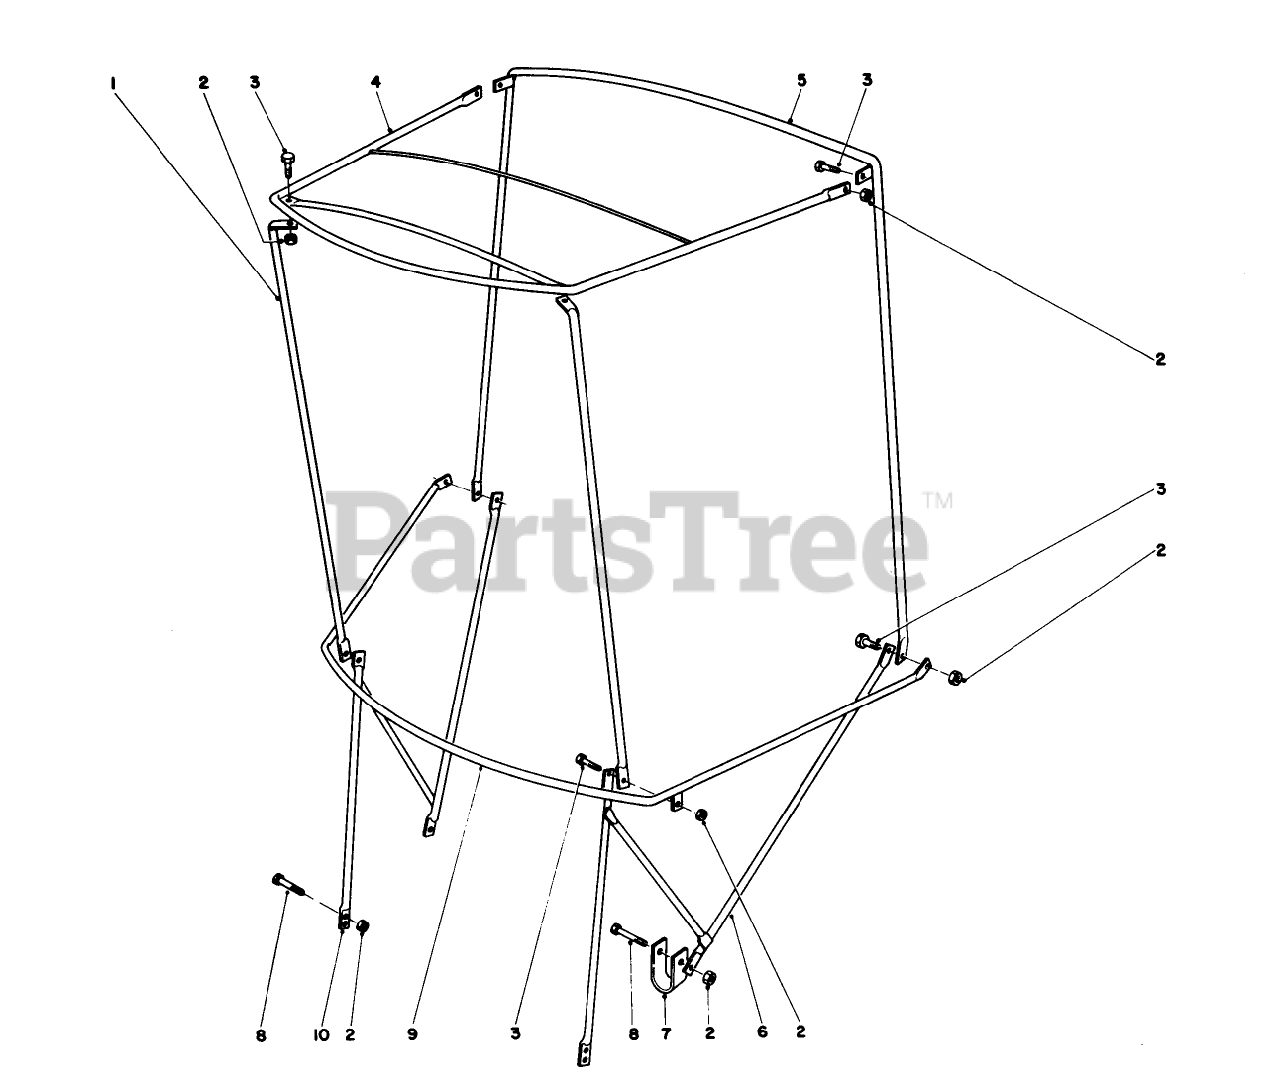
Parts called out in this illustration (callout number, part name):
2	NUT-HEX, SIDE DEFORM
3	SCREW-HH
8	SCREW-HH
